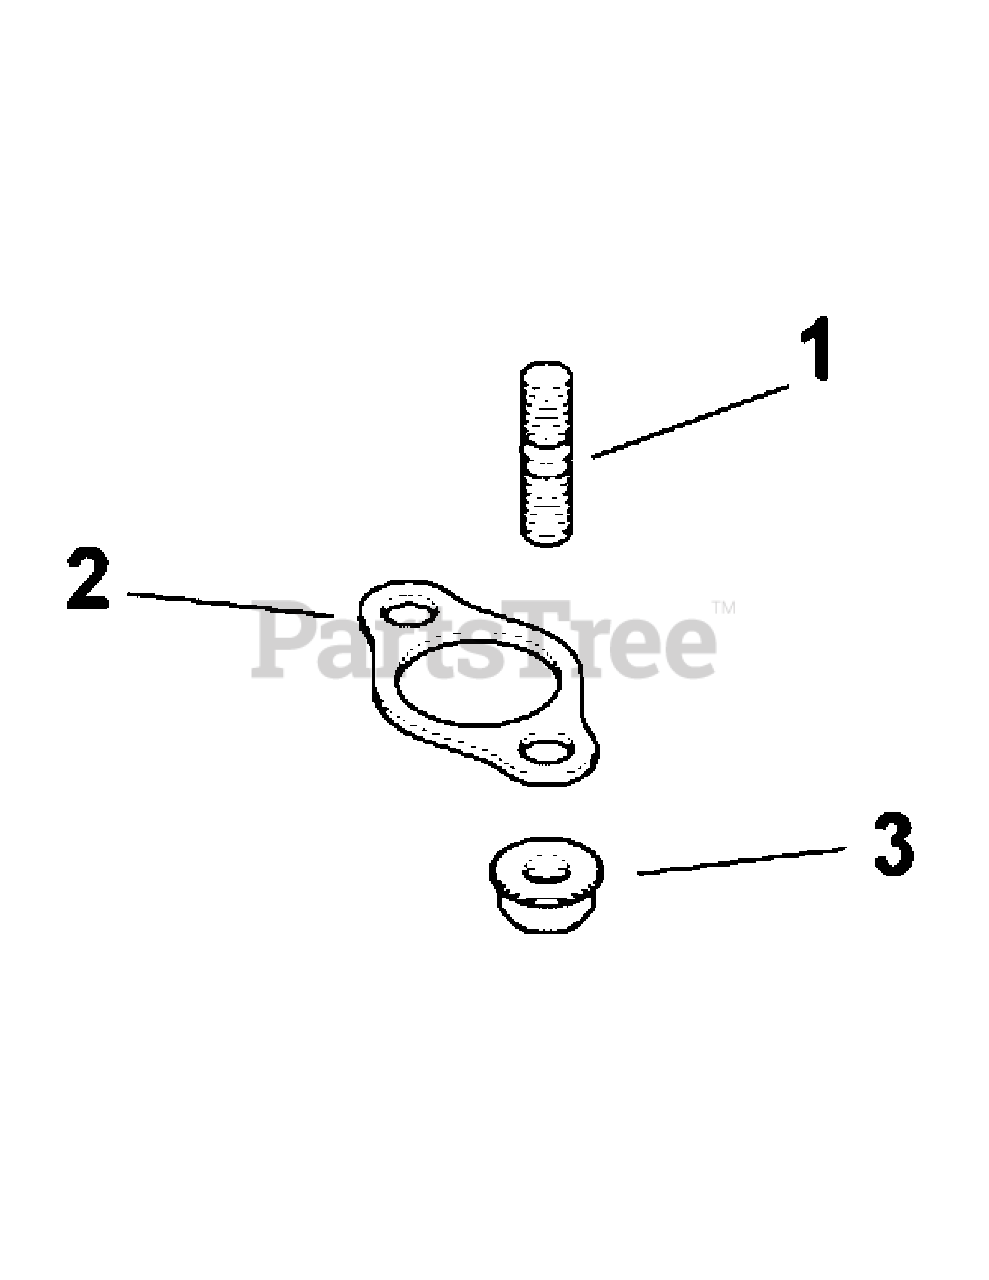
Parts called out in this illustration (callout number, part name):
1	STUD M8X1.25X33
2	GASKET, EXHAUST
3	NUT, FLG M8X1.25
